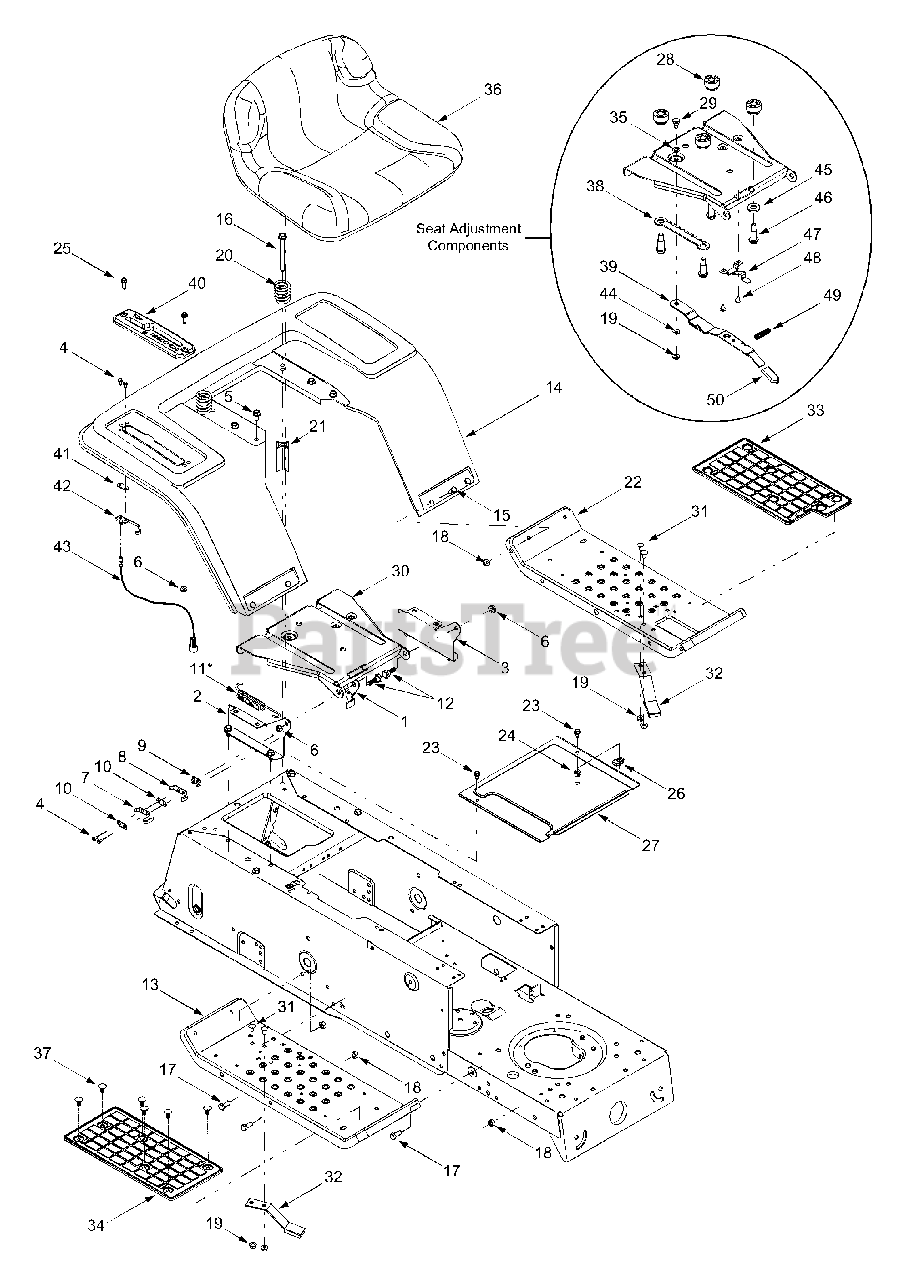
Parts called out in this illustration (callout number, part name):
1	Seat Lift Bracket
4	Self-tapping Screw, #8-18 x .50
5	Self-tapping Screw, 5/16-12 x .75
6	Flange Lock Nut, 5/16-18
7	Outer Seat Spring Switch
8	Inner Seat Spring Switch
9	Insulator Plate Boss
10	Insulator Plate
11	Extension Spring, .75 x 5.31
12	Shoulder Screw, .437 x .286
16	Self-tapping Screw, 5/16-18 x 3.5
17	Hex Screw, 5/16-18 x .75
18	Nylon Lock Nut, 5/16-18
19	Flange Lock Nut, 1/4-20
20	Compression Spring, 1.314 x 2.55
24	Snap Bushing, 1/4
25	Self-tapping Screw, 1/4-20 x .75
26	U-Clip Nut, 1/4-20
29	Shoulder Screw, .340 x .285, 1/4- 20
32	Blade Spindle Brake Assembly
33	LH Rubber Foot Pad
34	RH Rubber Foot Pad
35	Flat Washer, .344 x .62
36	Low Back Seat, Black
37	Ratchet Clip, .250 Dia
38	Seat Select Bracket
39	Seat Adjustment Lever
40	Speed Index Bracket
41	Insulator Nut Plate
42	Spring Switch
43	Wire Extension, Reverse
44	Spring Washer
45	Flat Washer, .531 x 1.062 x .134
46	Shoulder Screw, .50 x .925, 3/8-16
48	Screw, #10-16 x .375
49	Compression Spring
